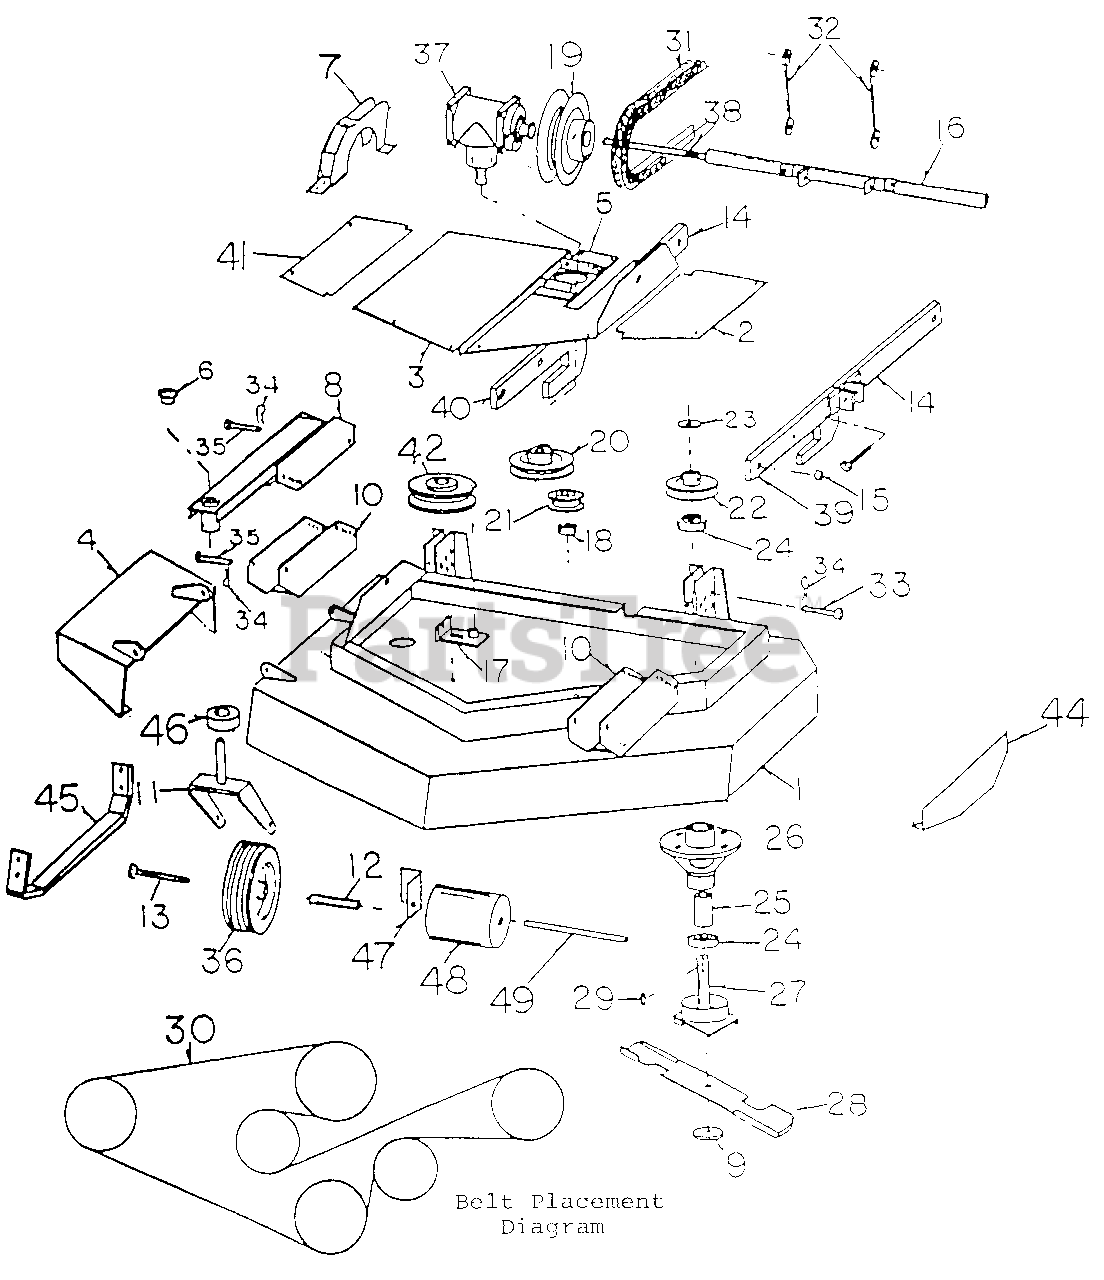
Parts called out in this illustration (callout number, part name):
1	MOWER DECK
2	COVER (Small)
3	COVER (Large)
4	FOOT GUAD
5	GEAR BOX MOUNT
6	GAUCE WHEEL BEARINGS
7	BET GUARD
8	GAGE WHEEL IOUNT
9	SPRING WASHER
10	BRACKET, GAGE WHEEL MOUI
11	FORK GAGE WHEEL
13	AXLE BOLT
14	DECK LIT ARM BACI ADJUSTABLE
15	BUSHING, DECK LIFT ARM
16	CROSS BAR
17	BELT TICHTENER
18	SPACER IDLER
19	PULLEY GEAR BOX (Input)
20	PULLEY GEAR BOX (Output)
21	5' IDLER
22	PULLEY SPINDLE
23	WASHER SPINDLE
24	BEARING, SPINDLE
25	SPACER SPINDLE
26	HOUSING SPINDLE
27	SHAFT SPINDLE
29	KEY SPINDLE
30	BELT, DECK
31	BELT, DRIVE
32	CABLE DECK
33	PIN, DECK
34	HAIR PIN
35	PINS, CAGE WHEEL
36	GAGE WHEEL
37	GEAR BOX
38	CROSS BAR PIN
39	DECK LIFT ARM FRONT ADJUSTABLE L.H
40	DECK LIFT ARM FRONT ADJUSTABLE R.H
41	COVER, RIGHT HAND SIDE
42	PULLEY, IDLER LARGE
44	SHOE LEFT HAND SIDE
45	SHOE RIGHT HAND SIDE
46	SET COLLAR
47	ROLLAR BRACKET
48	RUBBER ROLLAR
49	ROLLAR SHAET
